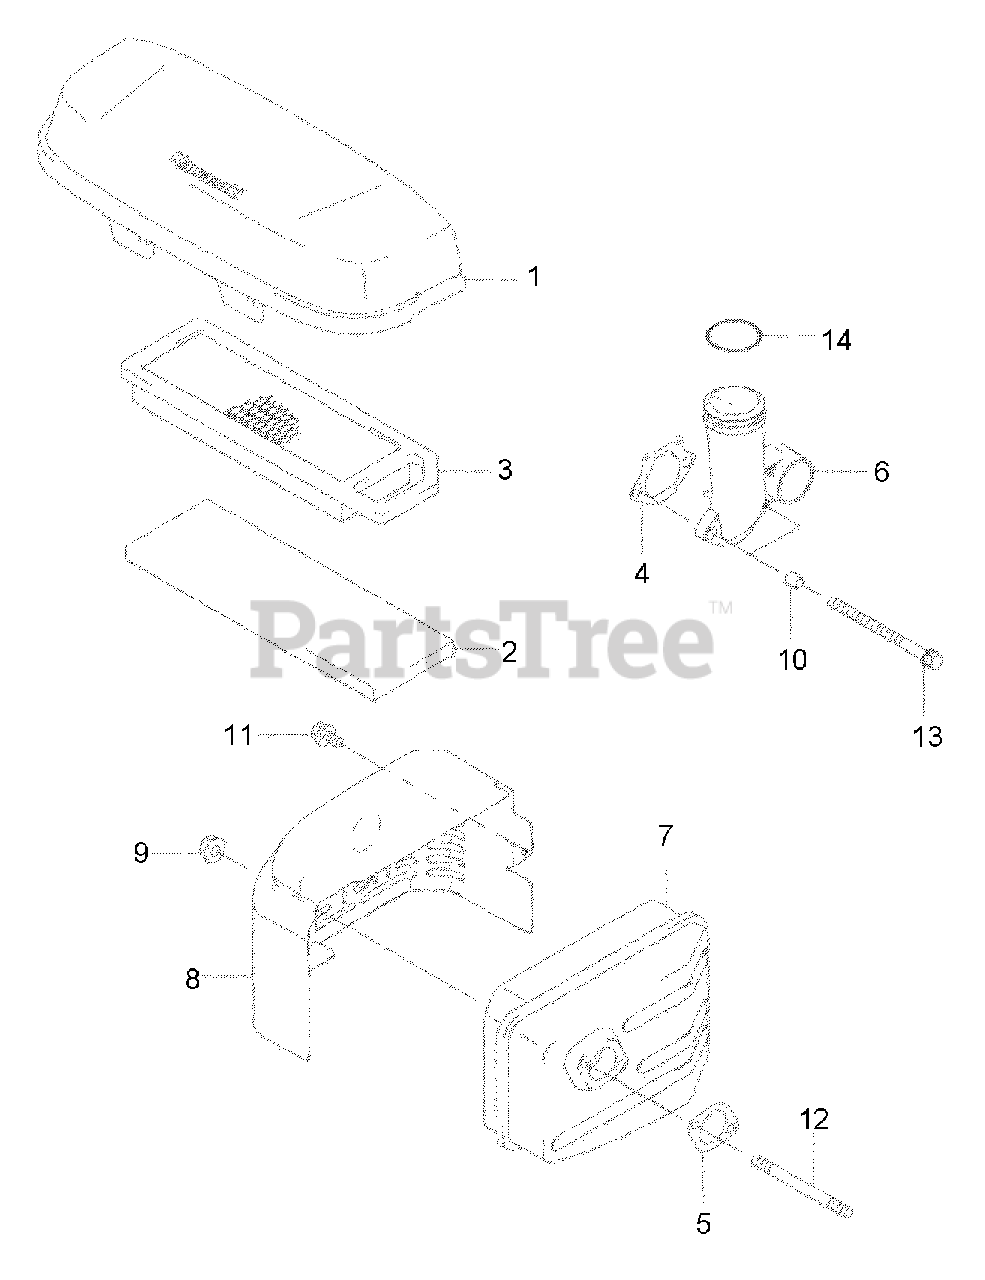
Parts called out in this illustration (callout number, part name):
1	Air Filter Case
2	Pre Filter Element
3	Air Filter Element
4	Intake Pipe Gasket
5	Muffler Gasket
6	Intake Pipe
7	Muffler
8	Muffler Cover
9	Nut
10	Spacer, 6.2x7.8x8
12	Stud Bolt
13	Bolt
